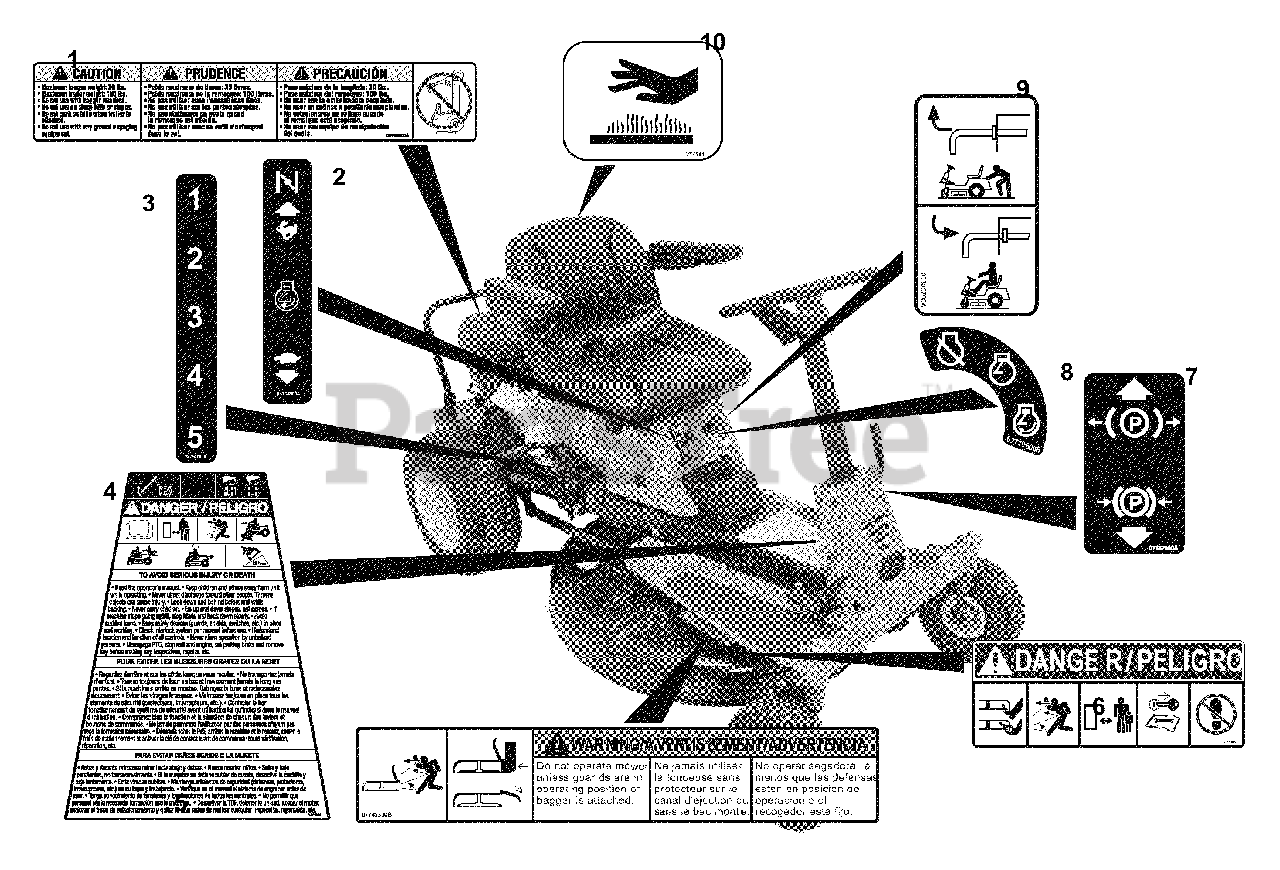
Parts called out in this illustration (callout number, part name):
1	DECAL-HITCH 100#
2	DECAL-THROTTLE RER/SPORT
3	DECAL, 5 POSITION CUT HEIGHT
4	DECAL-RER WARNING
5	DECAL, WARNING
6	DECAL, MOWER PAN DANGER
7	DECAL, PARKING BRAKE LEVER
8	DECAL - IGNITION
9	DECAL, TRANS DISCONNECT
10	DECAL, HOT SURFACE
